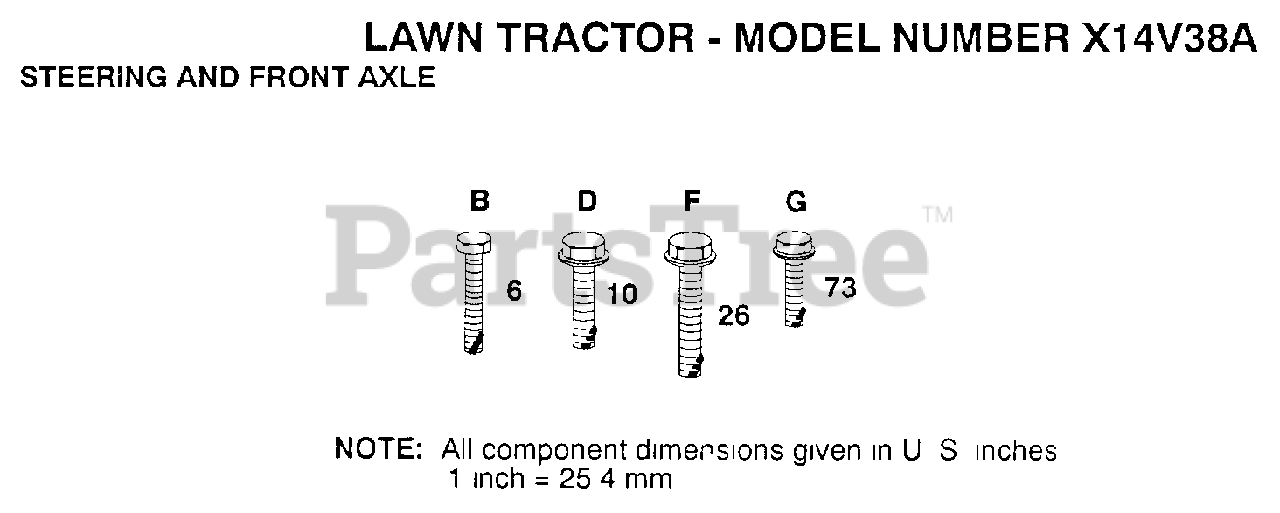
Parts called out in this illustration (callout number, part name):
6	SCREW LT
10	SCREW LT
26	SCREW
73	SCREW LT
